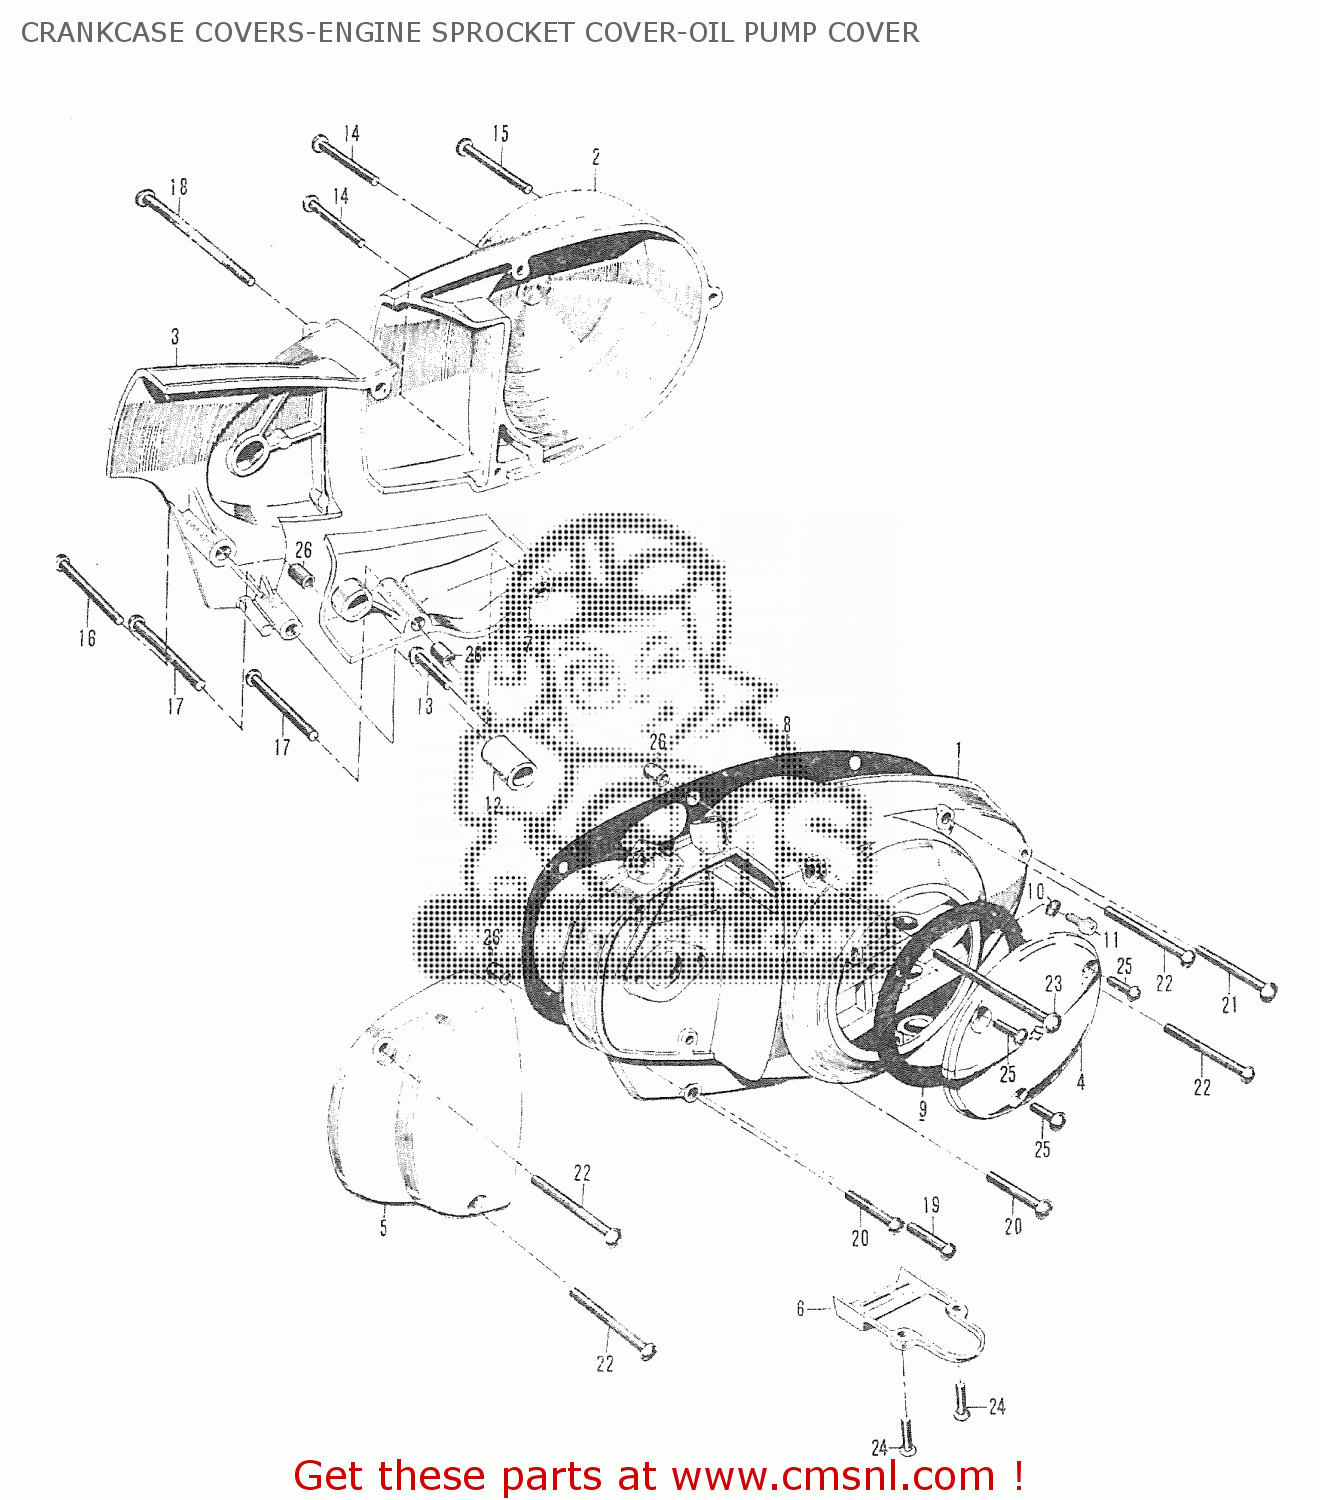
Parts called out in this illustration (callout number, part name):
1	CRANKCASE RIGHT COVER
2	COVER,MAGNETO
3	ENGINE SPROCKET COVER
4	CLUTCH RELEASE ADJUSTING CAP
5	OIL PUMP COVER
6	COVER, CLUTCH RELEASE
7	GEAR SHIFTING SHAFT HOLDER
8	CRANKEASE RIGHT COVER GASKET
9	CLUTCH RELEASE ADJUSTING CAP G (TC250; I.D.=78(3.07). O.D.=110(4
10	GASKET(6.2X11X1) (NAS)
11	PLUG
12	ENGINE SPROCKET COVER CHAIN BUFFER
13	CROSS HEAD SCREW
14	CROSS HEAD SCREW
15	CROSS HEAD SCREW
16	CROSS HEAD SCREW
17	CROSS HEAD SCREW
18	CROSS HEAD SCREW
19	STRONG CROSS HEAD SCREW
20	STRONG CROSS HEAD SCREW
21	STRONG CROSS HEAD SCREW
22	STRONG CROSS HEAD SCREW
23	STRONG CROSS HEAD SCREW
24	CROSS HEAD SCREW
25	CROSS HEAD SCREW
26	DOWEL PIN
